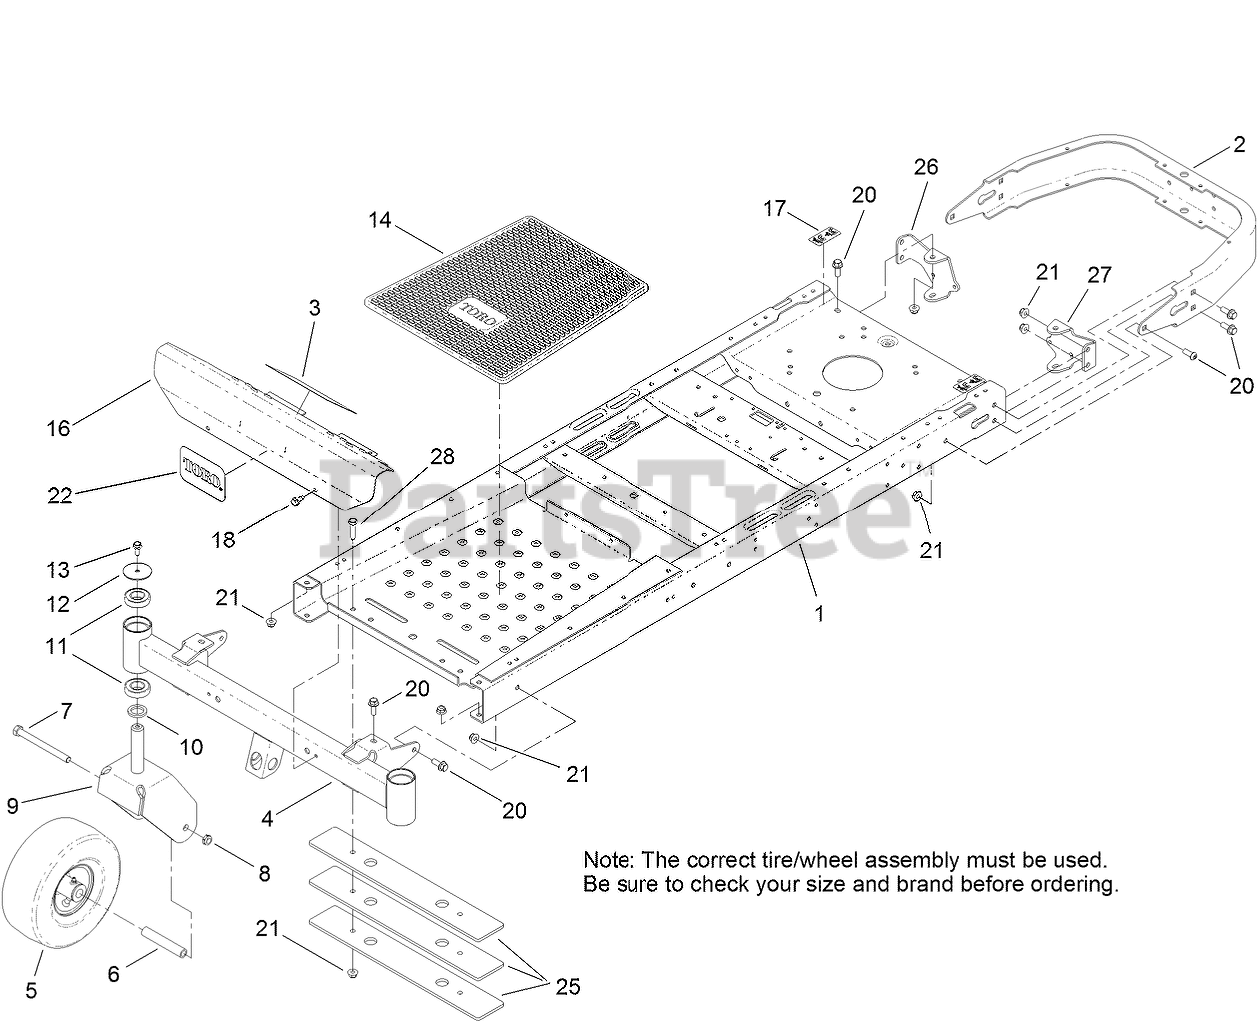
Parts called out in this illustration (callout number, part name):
2	BUMPER-REAR
3	DECAL-DANGER
4	AXLE-FRONT
5	CASTER WHEEL ASM (CST)
5	CASTER WHEEL ASM (Kenda)
6	BUSHING-SPANNER
7	SCREW-HH
8	NUT-LOCK, NI
9	FORK-CASTER
10	WASHER-THRUST
11	BEARING-BALL
12	WASHER
13	SCREW-HHF
14	MAT-FLOOR
16	FOOTREST
17	DECAL-BYPASS
18	SCREW-HWHTF
20	SCREW-HHF
21	NUT-HF, NI
25	PLATE-WEIGHT
26	MOUNT-HYDRO, REAR (RH)
27	MOUNT-HYDRO, REAR (LH)
28	SCREW-HH
